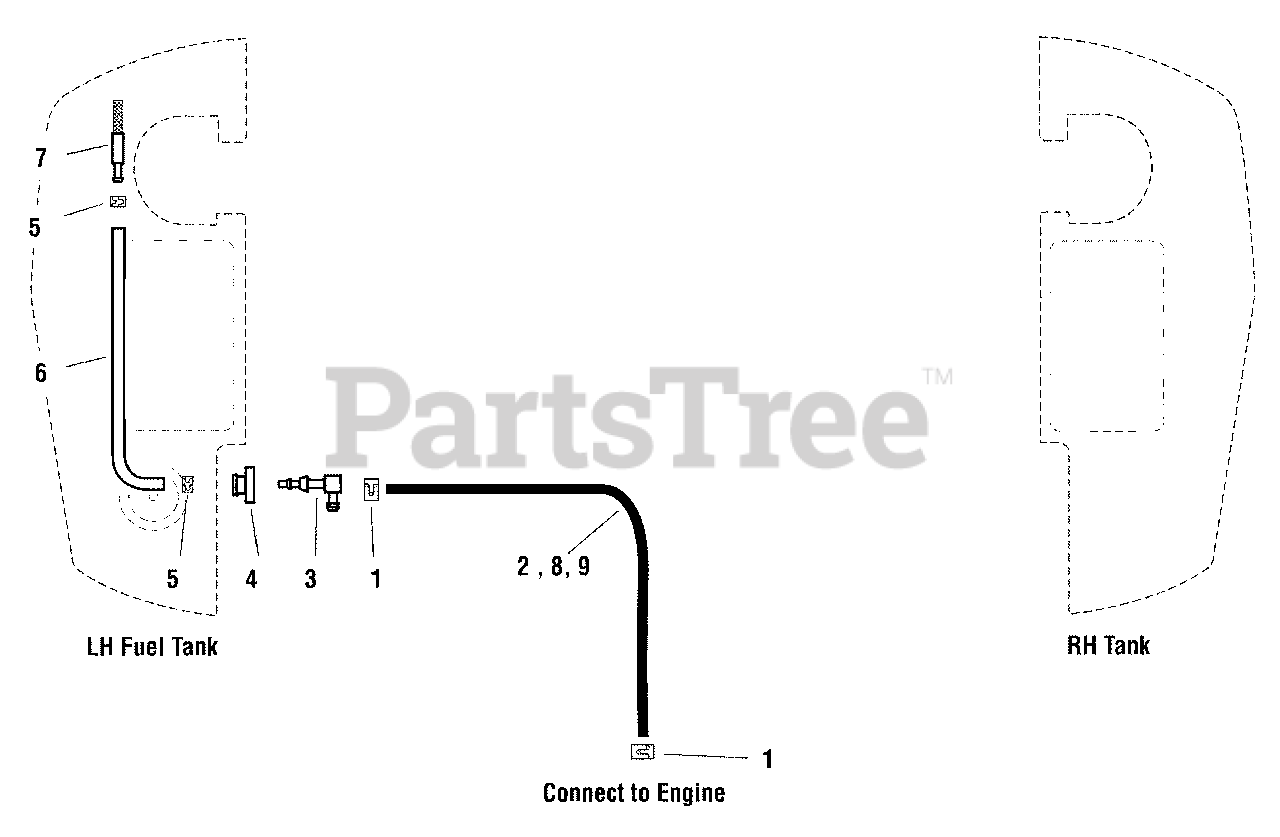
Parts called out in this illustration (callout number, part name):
1	CLAMP, HOSE, EXTERNAL, 1/2 - RED
2	HOSE, 1/4" FUEL, 22.00"
3	ELBOW FITTING
5	HOSE CLAMP
6	HOSE, 26"
7	SCREEN FITTING
8	HOSE, 1/4" FUEL, 31.00
9	HOSE, 1/4" FUEL, 25.00"
